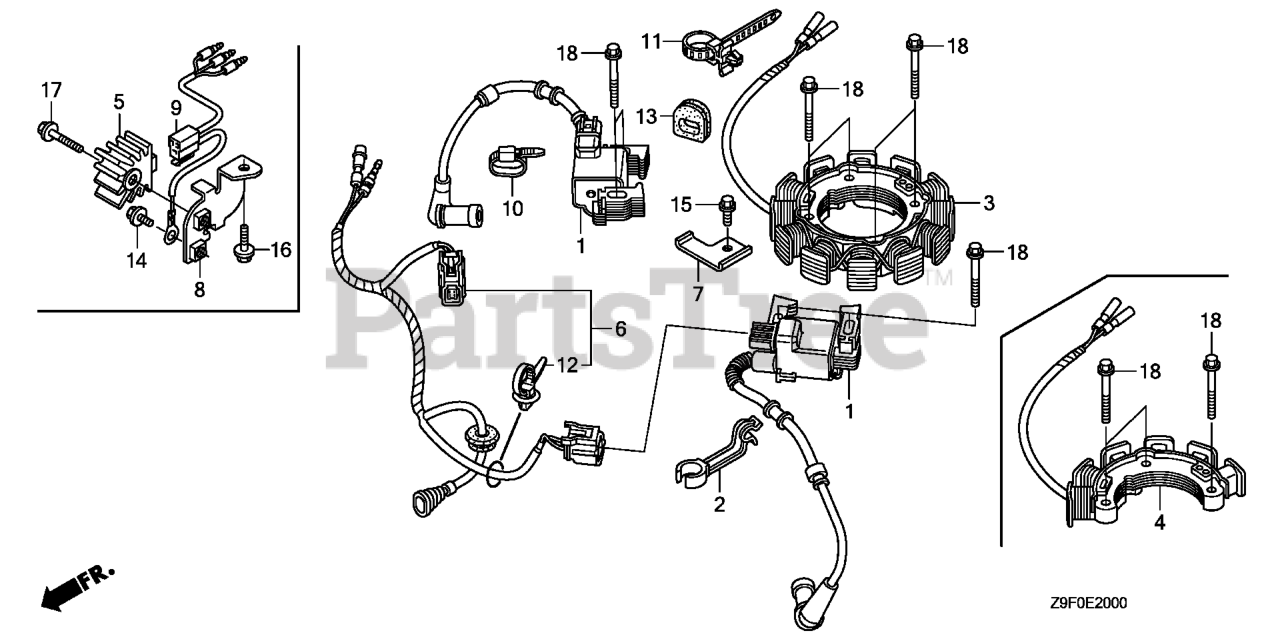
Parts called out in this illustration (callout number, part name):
1	COIL ASSY., IGNITION
2	CLAMP, IGNITION WIRE
3	COIL ASSY., CHARGE (26A)
6	WIRE HARNESS ASSY., ENGINE
7	BRACKET, HARNESS
10	BAND, WIRE (95MM)
11	STRAP, CABLE (105MM) *NH1* (Honda Code 1685536). (BLACK)
12	CLIP, HARNESS BAND (145MM) (BLACK)
13	GROMMET, CORD
15	BOLT, FLANGE (6X12) Use up to Engine SN 1543277.
18	BOLT, FLANGE (6X32)
